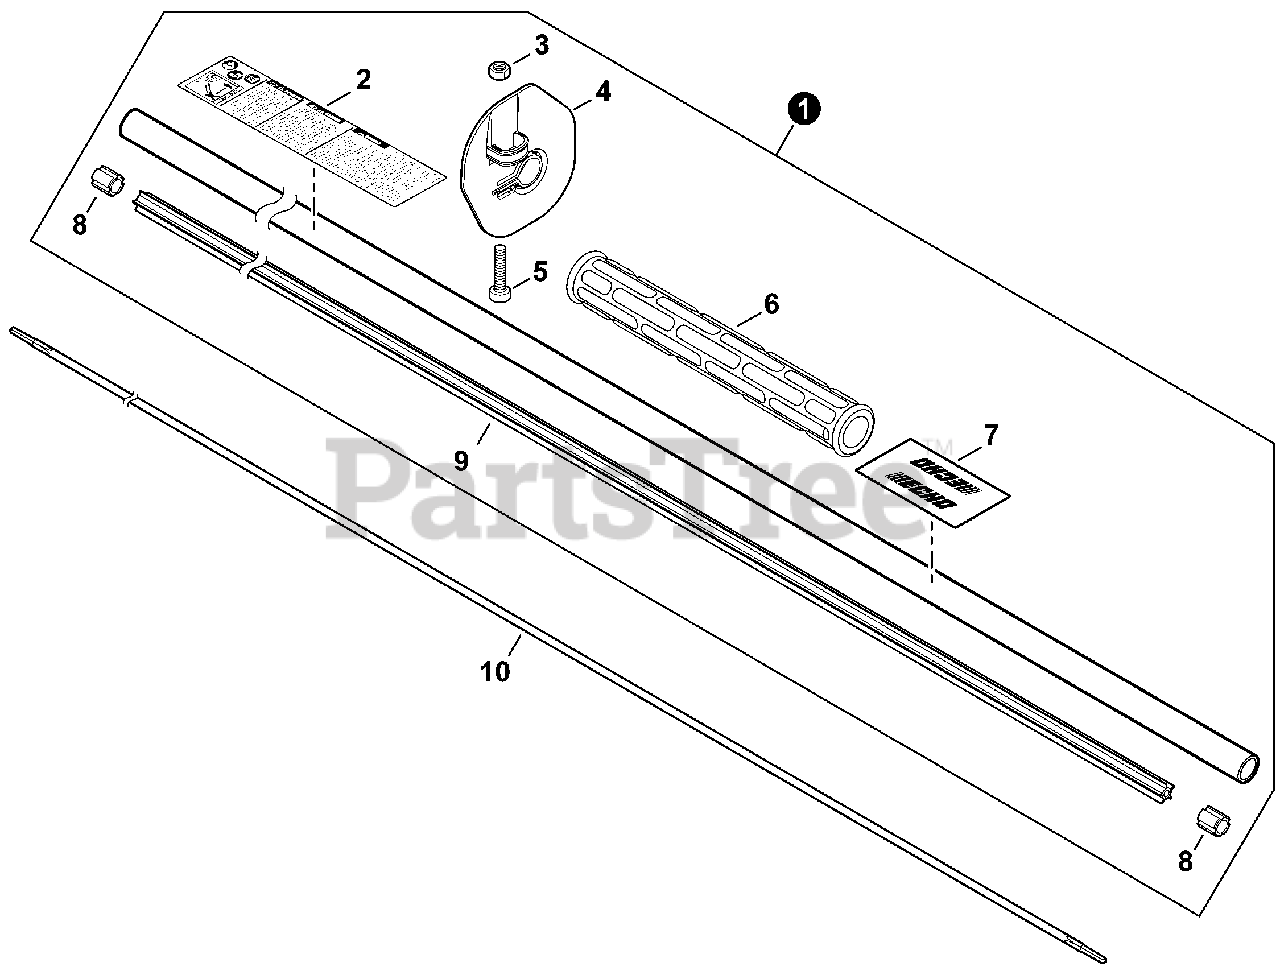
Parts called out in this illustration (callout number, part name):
1	MAIN PIPE ASSY
2	LABEL, CAUTION
4	GUARD, HAND
5	BOLT, TORX 5×20
6	GRIP, FRONT
7	LABEL, HANDLE LOCATION
9	LINER, FLEXIBLE 21.6×1420
10	DRIVESHAFT - FLEXIBLE
